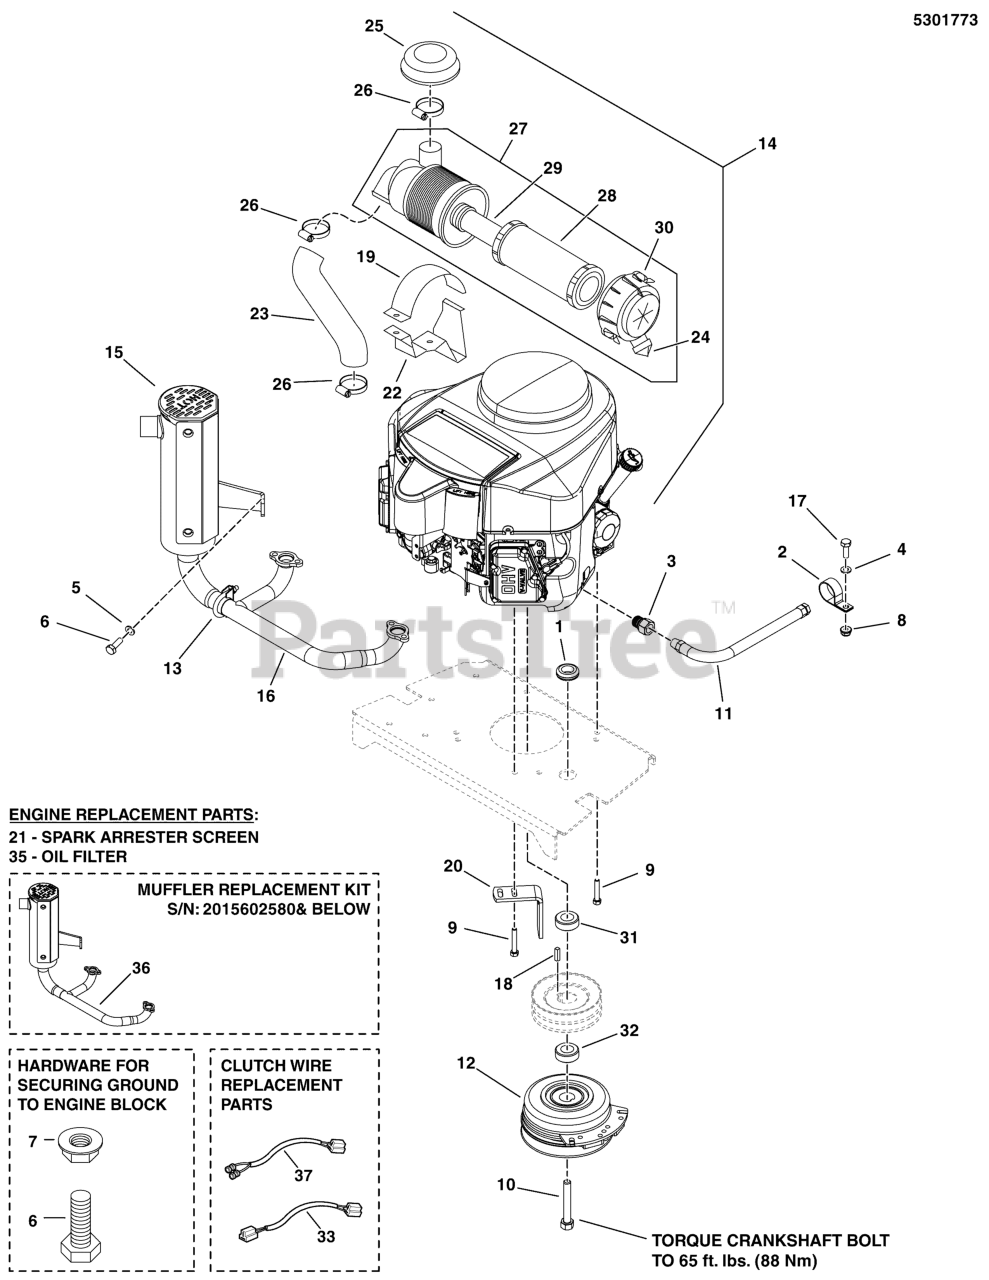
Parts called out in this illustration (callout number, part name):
1	GROMMET, 7/8
2	CLAMP, VINYL INSULATED
3	ADAPTER-OIL DRAIN
4	WASHER, 1/4 SAE
5	WASHER, 5/16" SAE
6	BOLT, M8-1.25 X 20MM GD8.8
7	NUT, M8-1.25 SERR. FLANGE, CZ
8	NUT, 1/4-20 HEX NYLOCK FLANGE
9	BOLT,HEX FLG, SER GD5 3/8-16X1-1/4,PATCH
10	BOLT, CRANKSHAFT, 7/16X2-1/2
11	HOSE, OIL DRAIN
12	* CLUTCH, 5218-134, WARNER
13	CLAMP, EXHAUST EXTENSION
14	ENGINE, KAWASAKI
15	MUFFLER
16	MANIFOLD
17	BOLT, 1/4-20 X 3/4 GD5 YZ
18	KEY, 1/4 SQ X 1
19	BRACKET PLATE, UPPER
20	ANCHOR, CLUTCH - BLK
21	SCREEN, SPARK ARRESTER
22	BRACKET PLATE, LOWER
23	AIR INLET TUBE
24	RUBBER DUST CAP
25	RAIN COVER
27	AIR FILTER ASSEMBLY
28	AIR FILTER, ELEMENT, PRIMARY
29	AIR FILTER, ELEMENT, SECONDARY
30	CAP END, FILTER CASE
31	SPACER, 1.13 X 1.75 X 1.03
32	SPACER, 1.13 X 1.75 X .50
33	WIRE HARNESS, JUMPER, WARNER CLUTCH
35	FILTER, OIL, KAWASAKI
36	KIT, MUFFLER & MANIFOLD
37	KIT, CLUTCH WIRE REPAIR
